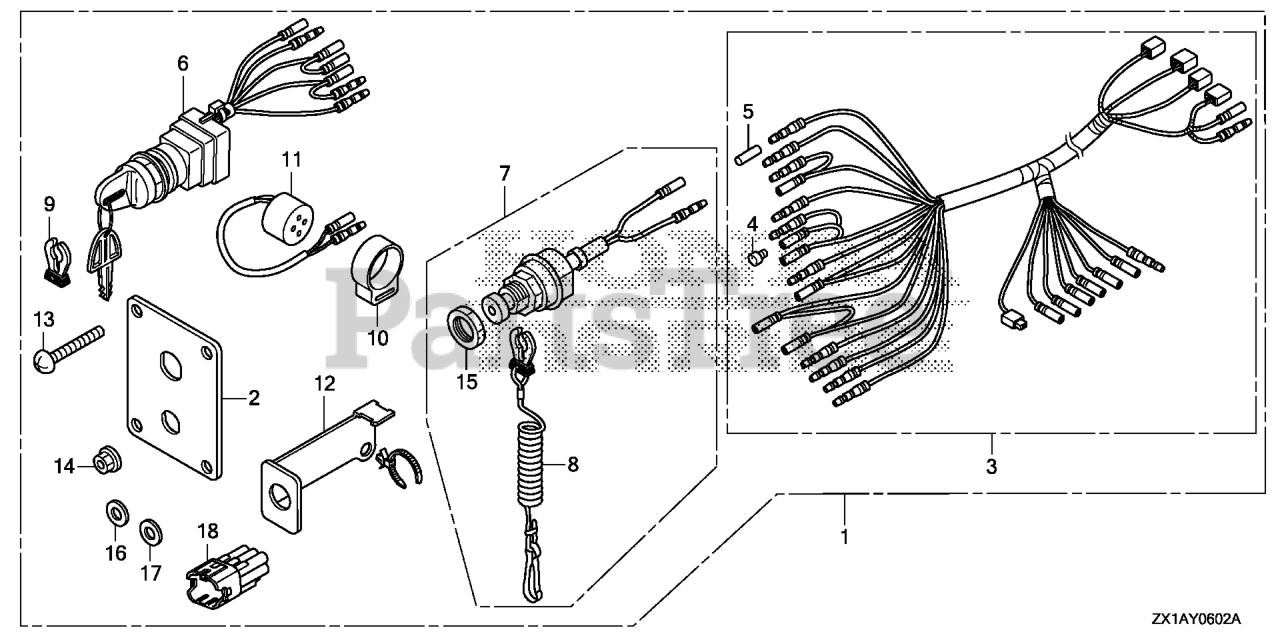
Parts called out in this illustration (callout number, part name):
1	PANEL KIT, SWITCH (SINGLE)
1	PANEL KIT, SW
2	PANEL, CONTROL (SINGLE)
3	HARNESS ASSY., SWITCH PANEL
4	PLUG, CONNECTOR (INNER) (TROLLING CONTROL)
5	PLUG, CONNECTOR (OUTER) (ENGINE NO.)
6	SWITCH ASSY., COMBINATION
7	SWITCH ASSY., EMERGENCY STOP (SINGLE)
8	WIRE, EMERGENCY
9	CLIP, EMERGENCY LOCK
10	SUSPENSION, AUDIBLE PILOT
11	BUZZER, WARNING
12	BRACKET
13	SCREW, PAN (5X40) DUAL QTY = (8) (SINGLE)
14	NUT, FLANGE (5MM)
15	NUT
16	WASHER, PLAIN (5MM)
17	WASHER, SPRING (5MM)
17	WASHER, SPG (5MM)
18	DUMMY, WATERPROOF CONNECTOR (GREEN)
